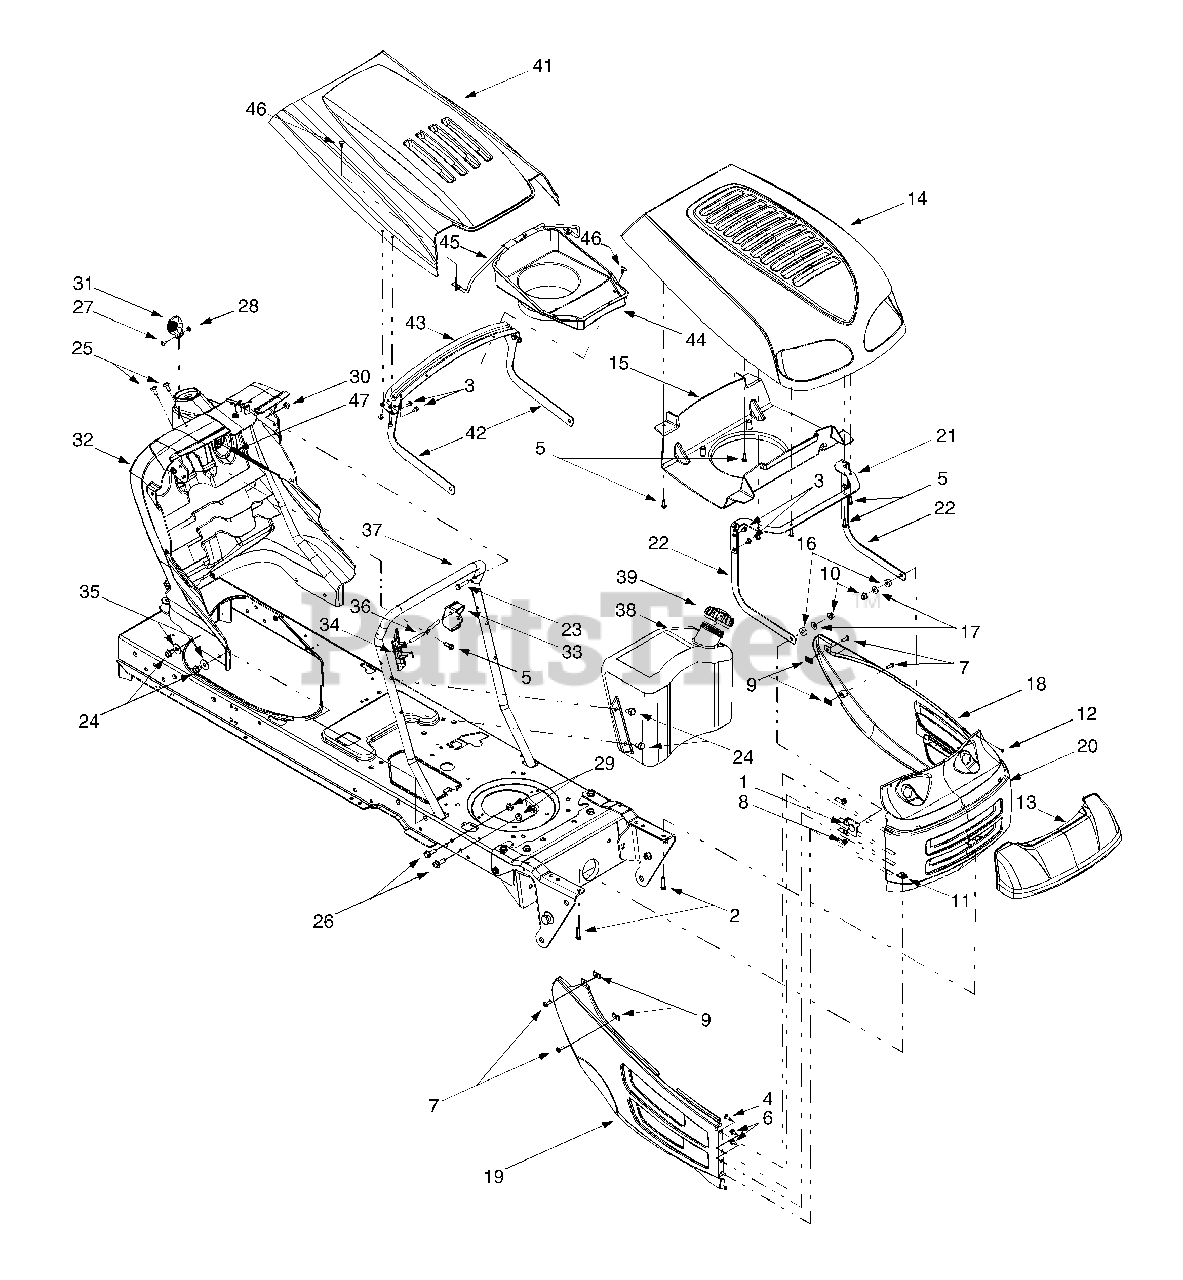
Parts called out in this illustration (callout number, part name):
2	Hex Cap Screw, 5/16-18 x 1.25
3	Self-tapping Screw, 1/4-20 x .5
4	Hex Cap Screw, 1/4-20 x .62
5	Self-tapping Screw, 1/4-15 x .75
6	Screw, 1/4-15 x .75
7	Phillips Pan Screw, 1/4-20 x .75
8	Hex Sems Nut, 1/4-20
9	U-type Speed Nut, 1/4-20
10	Flange Lock Nut, 3/8-16
11	U-nut, 5/16-18
12	Retainer Nut, 3/8
13	Headlight Lens
14	Hood, 7-style, Red
15	Hood Plenum, 7-style
16	Rubber Washer, .87 x .33
17	Bell Washer, .401 x .87 x .063
24	Self-tapping Screw, 5/16-18 x .625
25	Truss Phillips Screw, 1/4-20 x .625
26	Hex Washer Screw, 5/16-18 x .625
27	Truss Phillips Screw, #8-32 x .375
28	Hex Nut, #8-32
29	Flange Lock Nut, 5/16-18
30	Hex Flange Lock Nut, 1/4-20
31	Throttle Control Knob
32	Dash Panel
33	Parking Brake Button
34	Plastic Plug
35	Flat Washer, .349 x 1.0 x .063
36	Pivot Rod
39	Fuel Cap
45	Heat Shield Support Rod
46	Ratchet Clip
47	Choke Cable/Knob
